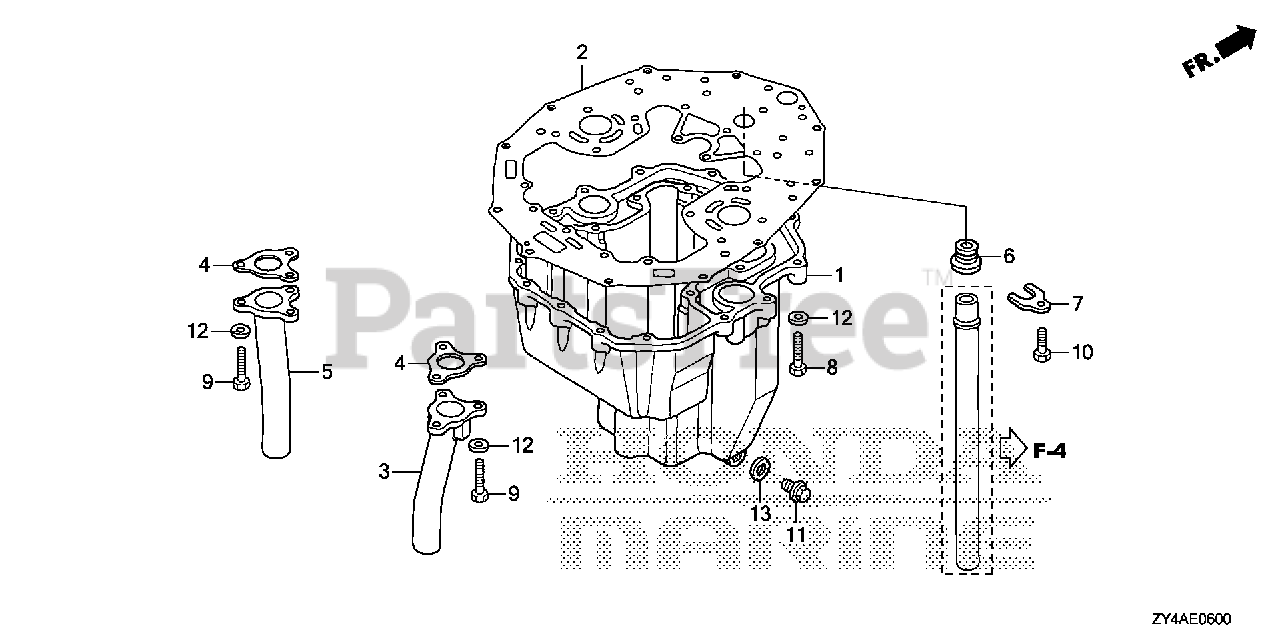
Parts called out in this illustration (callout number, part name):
1	PAN, OIL *TGRAY* (GRAY)
2	GASKET, OIL PAN
3	PIPE, R. EX.
4	GASKET, EX. PIPE
5	PIPE, L. EX.
6	GROMMET, WATER TUBE
7	PLATE, WATER TUBE
8	BOLT, HEX. (8X35)
9	BOLT, HEX. (8X28)
10	BOLT, HEX. (6X16)
11	BOLT, DRAIN PLUG
12	WASHER, PLAIN (8MM)
13	WASHER, DRAIN PLUG (12MM)
